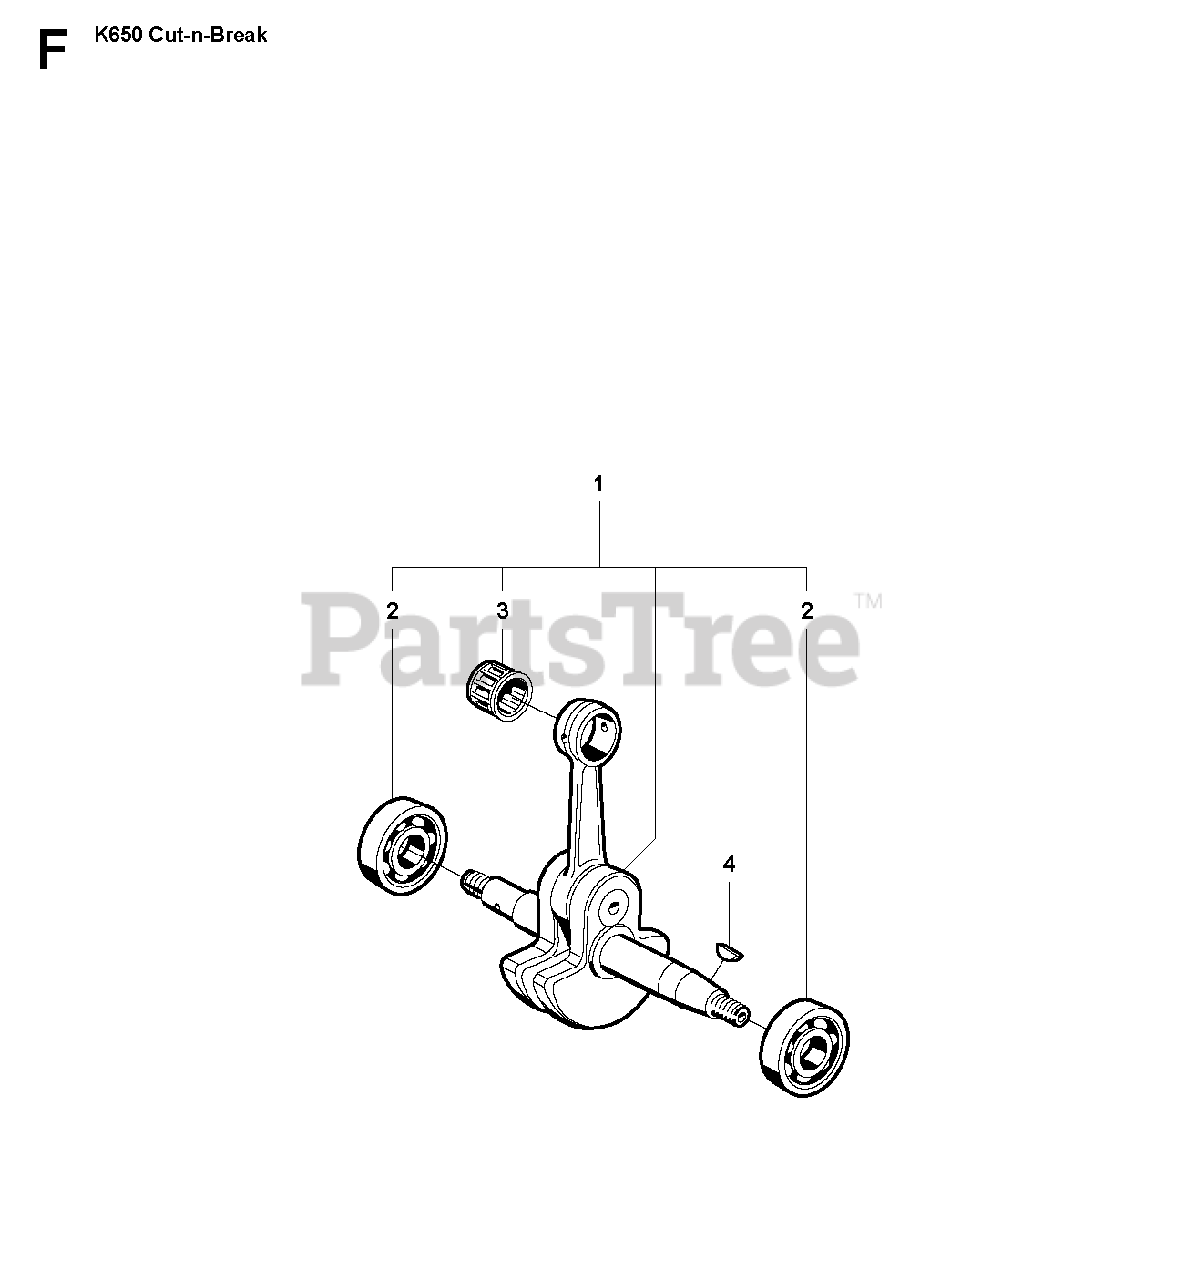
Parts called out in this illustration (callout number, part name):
1	CRANKSHAFT ASSYIncl. 2, 3
2	BALL BEARING
3	NEEDLE BEARING
4	WOODRUFF KEY
